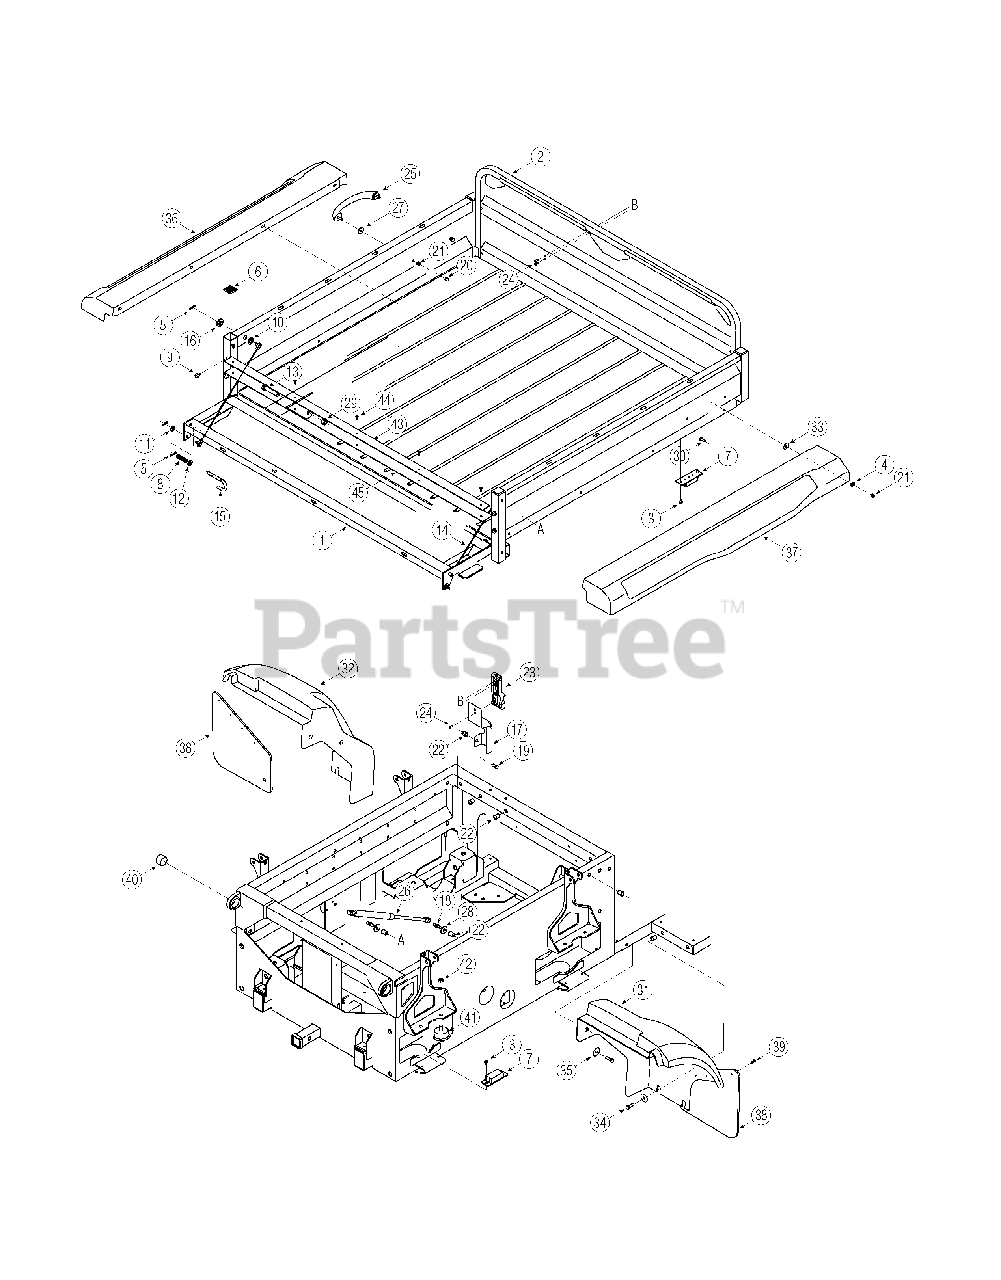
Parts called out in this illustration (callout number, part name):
3	Screw, Self-tapping, 1/4-20 x 0.500
4	Flat Washer,.271 x.630 x.065
5	Cotter Pin,.072 Dia x 1.13
7	Bumper, Extension Suspension
8	Compression Spring, .406 x .531 x 1.75 LG
9	Bumper, .62Dia x .3
10	Washer, Flat, .64 ID x 1.0 x .12
11	Washer, Flat, .344 x .750 x .120
12	Washer, Flat,.407 x.812 x.135
13	Screw, Hex, 1/2-13 x 2.5
14	Cable, LIft 16.16 LG
15	Handle, Deck Release
16	Spacer, Shoulder .625 Dia x .324 Dia
17	Bracket, Bed Latch Base
18	Stud, Ball 5/16-18
19	Hex Screw, 5/16-18 x .625, Gr5
20	Nut, Acorn 1/4-20 w/o Lock
21	Nut, Hex Lock, 1/4-20
22	Nut, Insert 5/16-18
24	Pop Rivet, 3/16
25	Handle, Bag w/Screw
26	Spring, Gas .91 Stroke
27	Washer, Flat .265 x .938 x .120
28	Washer, Flat.344 x 1.125 x.120
29	Hex Lock Nut, 1/2-13
30	Hex Screw, 1/4-20 x.75
31	Fender, Rear RH, Camo
32	Fender, Rear LH, Camo
33	Rubber Washer,.310 x 1.0 x.125
34	Hex Screw, 5/16-18 x 1.0
35	Bell Washer,.350 x 1.25 x.06
36	Bed Skirt Panel, LH, Camo
37	Bed Skirt Panel, RH, Camo
38	Rear Mud Flap
39	Pop Rivet,.188
40	Rubber Bushing, Bed Pivot
41	Bumper, Compression Suspension
42	Hex Lock Nut, M10-1.25
45	Tail Gate Seal Strip
